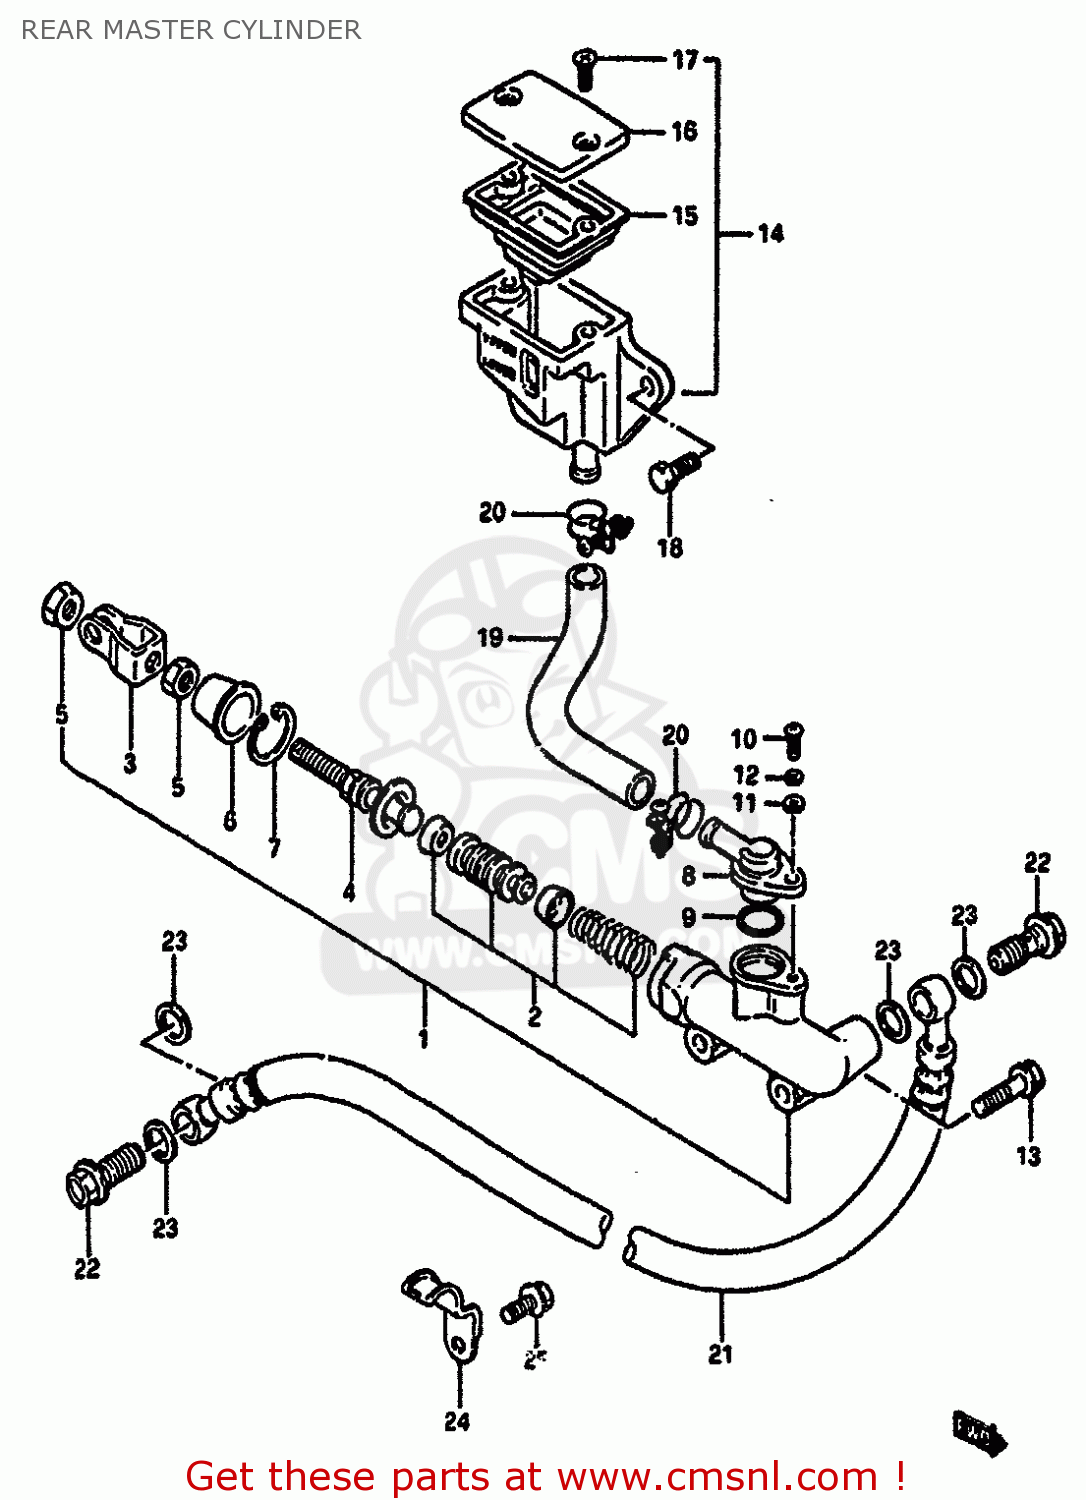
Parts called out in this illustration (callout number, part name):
1	CYLINDER ASSEMBLY,REAR MASTER
2	PISTON/CUP SET
3	YOKE
4	ROD,PUSH
5	NUT
6	BOOT
7	CIRCLIP
8	CONNECTOR
9	O RING
10	SCREW
11	WASHER
12	LOCK WASHER
13	BOLT 6X23
14	TANK ASSEMBLY,RESERVOIR
15	DIAPHRAGM
16	CAP
17	SCREW
18	BOLT
19	HOSE,RESERVOIR TANK
20	CLAMP
21	HOSE,REAR BRAKE
22	BOLT UNION
23	WASHER(10X15X1.5)
24	GUIDE,REAR BRAKE HOSE
25	BOLT
